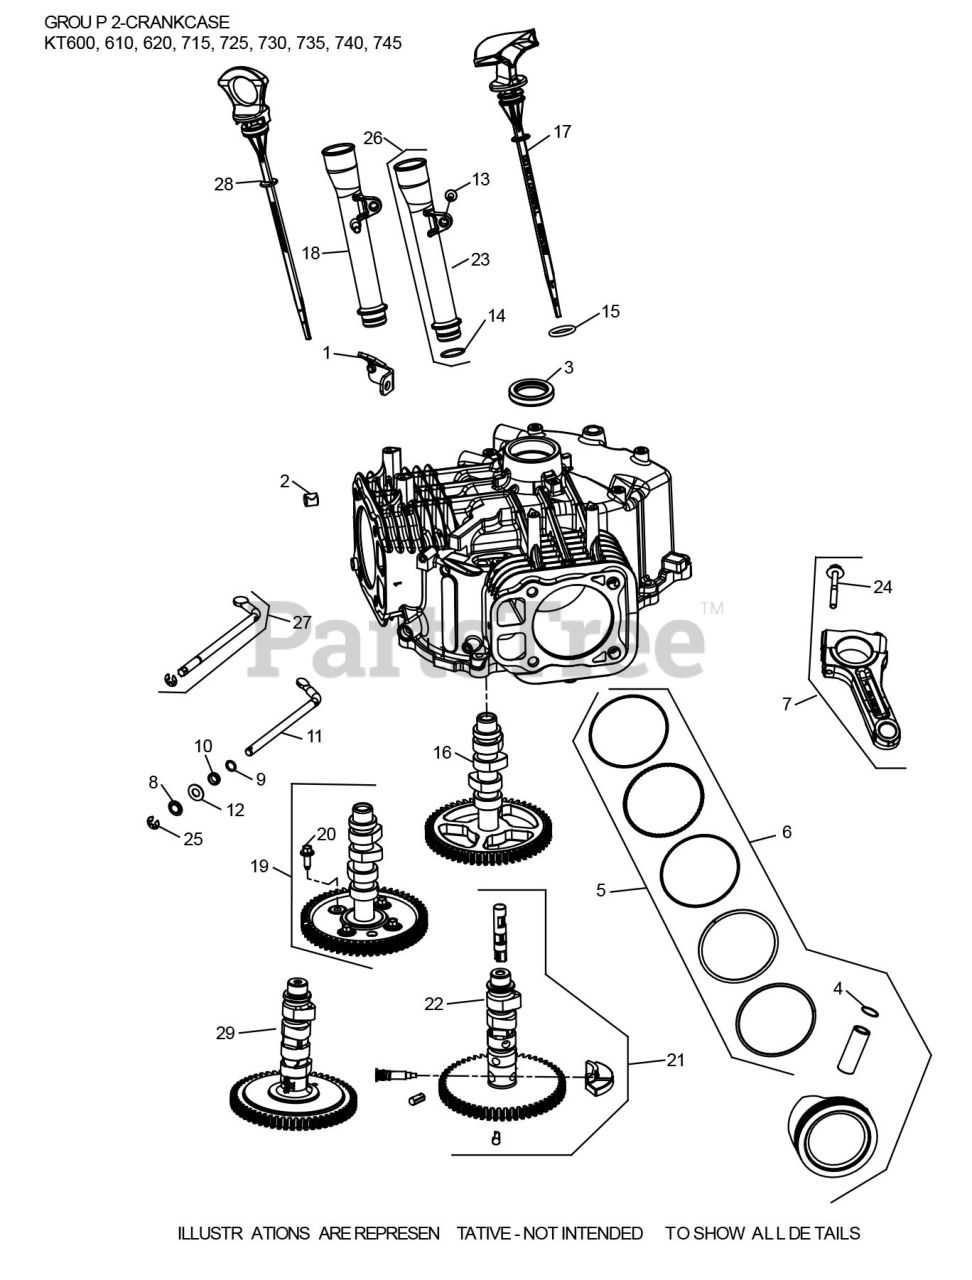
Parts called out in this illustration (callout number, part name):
1	BRACKET-OIL FILL TUBE
2	PIN-SPLIT DOWEL
4	RETAINER-PISTON
6	PISTON KIT (STD)
7	CONNECTING ROD ASSEMBLY
9	WASHER-1/4 FLAT
12	WASHER-9MM FLAT
15	O-RING DIPSTICK
16	CAMSHAFT ASSEMBLY
18	DIPSTICK TUBE
25	GOVERNOR SHAFT RETAINER CLIP
27	CROSS CARBURETOR SHAFT KIT
